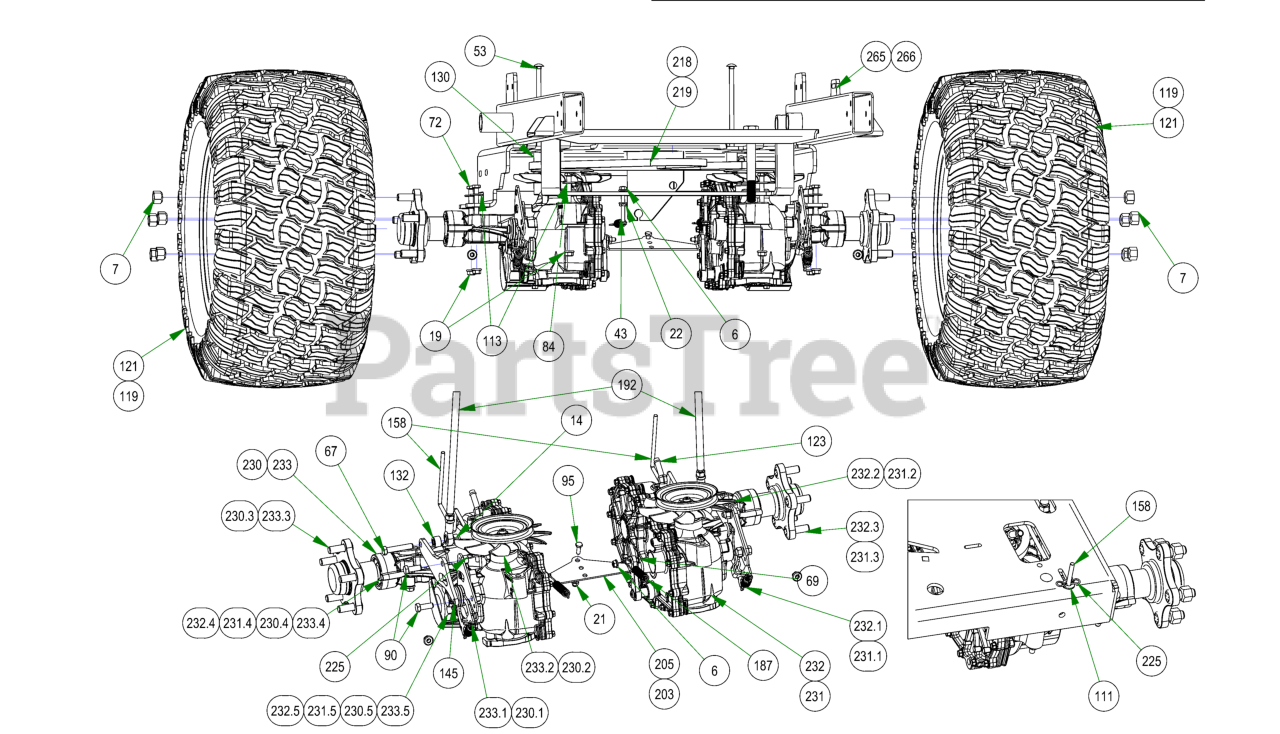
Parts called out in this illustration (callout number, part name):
6	1/4-20 NYL INSERT FLANGE LOCKNUT ZINC
7	Acorn Lug Nut
14	3/8-16 HEX NUT ZINC
19	5/16-18 NYLON INSERT FLANGE LOCKNUT ZINC
21	1/4-20 NYLON INSERT LOCKNUT ZINC
22	1/4-20 HEX SERRATED FLANGE NUT HARD/ZINC
31	1 1/2 x 3 Frame Plug
43	1/4-20 X 2 HEX CAP SCREW (GR.5) ZINC
53	5/16-18 X 6 CARRIAGE BOLT (GR.5) ZINC
67	3/8-16 X 2 HEX CAP SCREW (GR.5) ZINC
69	1/4-20 X 1 HEX CAP SCREW (GR.5) ZINC
72	5/16-18 X 3 HEX CAP SCREW (GR.5) ZINC
84	5/16-18 X 2-1/2 HEX CAP SCREW (GR.5) ZINC
90	3/8-16 X 1 GR 5 Hex Bolts Zinc
95	1/4-20 X 3/4 HEX CAP SCREW (GR.5) ZINC
104	3/8 SPLIT LOCKWASHER ZINC
111	1/4 USS FLAT WASHER (3/4 OD) ZINC
113	5/16 USS FLAT WASHER (7/8 OD) ZINC
119	23x9-12 Reaper Turf Tire & Wheel Assembly
121	23x11-12 Reaper Turf Assembly
123	ZT Fitting, 3/8 x 3/8 45 Degree, 4603-6-6
130	2017 Transaxle Spacer
132	ACS Spacer 3/4x3/8x1/2
145	Control Arm Plate 2019 Stand On
158	2019 Stand On Neutral Rod
187	Brake Spring
192	2019 Revolt Push Rod Assembly
203	2020 36" Brake Bracket 2020 36" Stand On
205	Brake Bracket
218	2019 Renegade Pump Belt
219	2019 Stand On Pump Belt (Timken# 47-2827)
230	ZT Transaxle Right 3100
230.1	Gold Transaxle Spring
230.2	2021 ZT/Maverick Transaxle Fan/Pulley Kit
230.3	ZT Transaxle Wheel Hub
230.4	2021 ZT/Maverick Transaxle Seal Kit (ZT-2800)
230.5	ZT Hydraulic Filter
231	ZT Transaxle Left 3100
231.1	Gold Transaxle Spring
231.2	2021 ZT/Maverick Transaxle Fan/Pulley Kit
231.3	ZT Transaxle Wheel Hub
231.4	2021 ZT/Maverick Transaxle Seal (ZT-2800)
231.5	ZT Hydraulic Filter
232	Compact Outlaw/Revolt Transaxle Left 3400
232.1	Gold Transaxle Spring
232.2	Fan/Pulley Kit for CZT Also for the 050-0075-01
232.3	5 Bolt Hub Kit
232.4	Seal Kit for 3400 Transaxle fits the 050-6000-01 / 050-6001-01
232.5	ZT Hydraulic Filter
233	Compact Outlaw/Revolt Transaxle Right 3400
233.1	Gold Transaxle Spring
233.2	Fan/Pulley Kit for CZT Also for the 050-0075-01
233.3	5 Bolt Hub Kit
233.4	Seal Kit for 3400 Transaxle fits the 050-6000-01 / 050-6001-01
233.5	ZT Hydraulic Filter
265	2019 Stand On Frame
266	2020 36" Stand On Frame
427	21/7x10 Reaper Tire-36 Revolt
